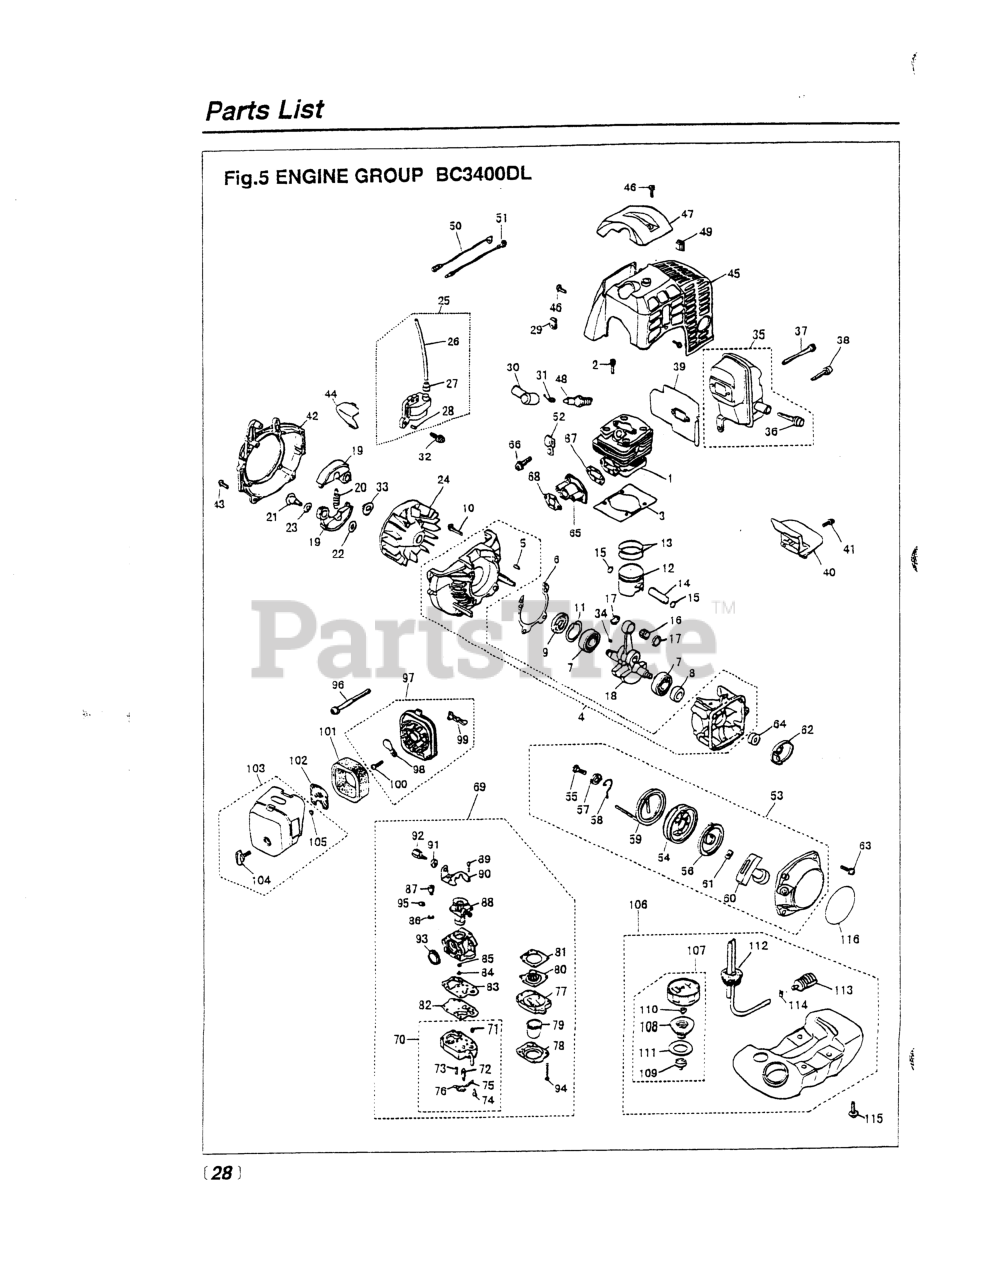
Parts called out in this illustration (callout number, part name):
1	CYLINDER
2	BOLT M5 x 20 (RPLS -12280)
3	GASKET, BASE
4	CRANKCASE COMPL (USE -21101)
5	PIN
6	GASKET
8	SEAL, OIL (RPLS 1100-21210)
9	SEAL, OIL (RPLS 1200-21220)
10	BOLT, M5 X 30
11	RING, SNAP, M32 x 1.2
12	PISTON
13	RING, PISTON
14	PIN, PISTON
15	RING, SNAP
16	BEARING
17	WASHER
18	CRANKSHAFT COMPL
19	SHOE, CLUTCH (RPLS -51110)
20	SPRING
21	SCREW
22	WASHER
23	WASHER (RPLS. -51240)
24	ROTOR
25	COIL ASSEMBLY
29	GROMMET
31	SPRING
32	BOLT, M4 x 22
34	KEY
35	MUFFLER ASSEMBLY
36	ARRESTER (RPLS 5850-15140)
37	BOLT, M5 x 60
38	BOLT (REPLACES 01252-30514)
40	PLATE (USE-15221)
41	SCREW,M5 X 14 (RPLS 1400-15510
43	BOLT M5 x 20 (RPLS -12280)
45	COVER
46	SCREW M5 x 12
47	GUARD
50	CORD
51	CORD, EARTH
52	CLAMP
53	RECOIL ASSEMBLY
54	REEL
55	SCREW
56	SPRING, SPIRAL
57	COLLAR
58	ARM
59	ROPE (USE 4810-75160)
60	KNOB
61	PLATE, STOPPER
62	PULLEY
63	SCREW, M6 x 14
66	SCREW, M5 X 20 (USE 5516-85510
67	GASKET, INSULATOR
68	GASKET, CARBURETOR
69	CARBURETOR ASSEMBLY
70	BODY, PUMP
72	VALVE, INLET
73	SPRING, METERING LEVER
74	SCREW, METERING LEVER PIN
75	PIN, METERING LEVER
76	LEVER
77	BODY, PURGE
78	COVER, PUMP
79	PUMP, PRIMING
80	DIAPHRAGM (USE 4810-81260)
81	GASKET, DIAPHRAGM
82	DIAPHRAGM
83	GASKET, PUMP
84	JET
85	RING, O
86	RING
87	SWIVEL
88	VALVE ASSY
89	SCREW
91	NUT, CABLE ADJUSTER
92	SCREW, CABLE ADJUSTER
93	RING, PACKING
94	SCREW
95	WASHER
97	BODY ASSEMBLY
98	PLATE, CHOKE
99	LEVER, CHOKE
100	SCREW (REPLACES 50030272)
101	ELEMENT
102	SCREEN
104	KNOB (RPLS -82220)
105	RING
108	HOLDER (USE -85300)
109	HOLDER, CAP
110	VALVE (NLA WHEN OUT)
111	PACKING
112	PIPE COMPLETE
113	FILTER ASSY
114	CLIP (REPLACES 2841-31280)
115	SCREW, M5 X 22
116	LABEL, RECOIL
